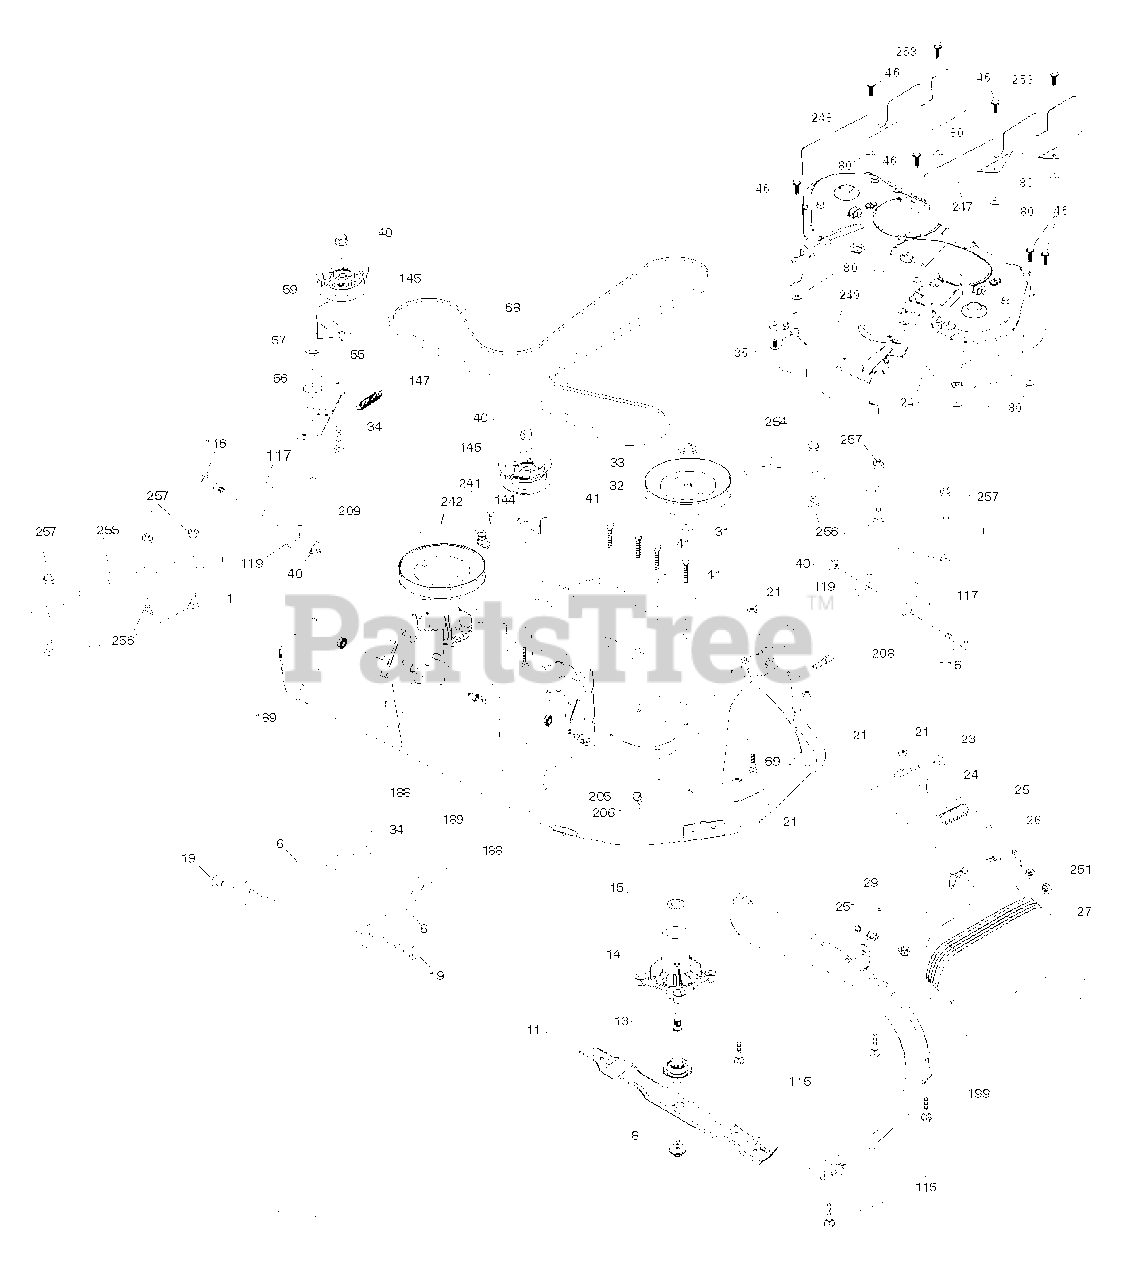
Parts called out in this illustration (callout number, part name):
1	DECK.38.WELDMENT.GREY
6	ARM.SUSPENSION.MOWER.R
8	BOLT.WASHER.ASM.7/16-2
11	BLADE.2 IN 1.38"DECK
13	SHAFT.ASM.MDRL.N/GREASE.38
14	HOUSING.MANDREL.4PT.
19	BOLT.SHOULDER
21	LOCKNUT
23	BRKT.DEFLECTOR.38"2005+
24	CAP-SLEEVE LT
25	SPRING.TORSION.DEFLECT
26	NUT PUSH M
27	SHIELD ASM.DFLCTR MWR.38-7"BLK
29	ROD.HINGE
31	WASHER.SPACER.MANDREL
32	PULLEY MANDREL
33	NUT.FLANGE.LOCK.TOP
34	BOLT.3/8-16X1.50
35	FASTENER.XMAS.TREE
40	NUT LOCK FLG 3/8-16 UNC
41	BOLT.HEX.WASHR.HED.313-18X1.19
46	SCREW.1/4-20X5/8
56	SPACER.RETAINER
57	SCREW 3/8-16X1
59	GUARD, BELT
68	BELT BELT 38' ELEC. DECK
69	BOLT
80	PALNUT 1/4
115	BOLT
116	BOLT M
117	WHEEL.GAGE.HALF.SPOKED
119	WASHER
144	KEEPER BELT
145	PULLEY.IDLER.48"PRIMARY
147	SPRING.MOWER.DRIVE.ELECTRIC
188	STUD.FASTNER.W/ANTI-ROTATE
189	NUT LOCK HEX FLANGE 5/16-18
199	BAFFLE.VORTEX.FRONT.38"
205	SCREW
208	SCREW 3/8-16X1/2
209	WASHER 12/32X2X10GA
241	SCREW.TT.#10-32X.5.3/8.FLANGE
242	PORT.WASHOUT
243	COVER DECK 38-7
247	SHIELD RIGHT
248	SHIELD LEFT
249	COVER CABLE CLUTCH
251	ELASTIC STRAP KIT
253	SCREW
254	PLATES.38 DECK RNFRC X431FRONT
255	PLATES.38 DECK RNFRC X431
256	SCREW.BUTTONHEAD.1/4-20X1
257	NUT T
